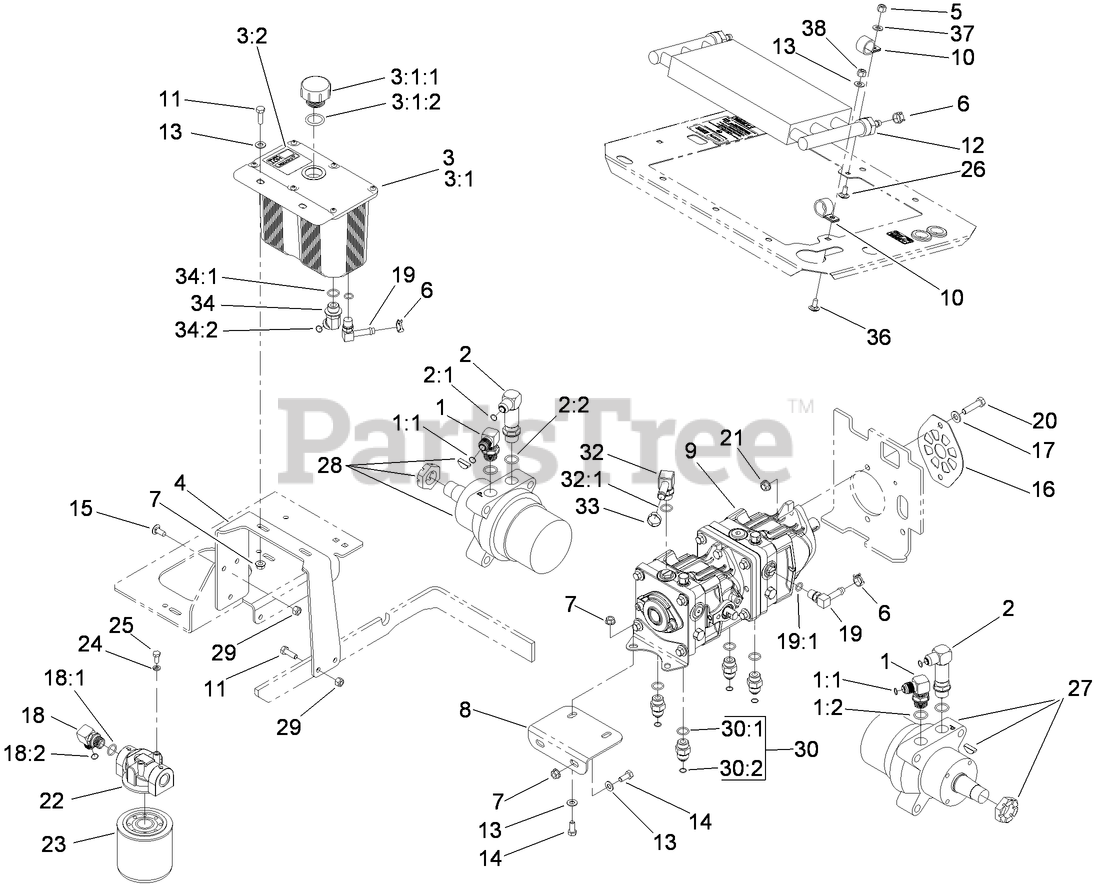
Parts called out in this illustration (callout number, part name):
1	FITTING-HYD, 90 DEG
1:1	O-Ring
1:2	O-RING
2	FITTING-ELBOW-90
2:1	O-Ring
2:2	O-RING
3	HYDRAULIC TANK ASM
3:1	TANK-HYDRAULIC
3:1:1	CAP-RESERVOIR, HYD
3:1:2	GASKET-CAP
3:2	DECAL-TANK, HYD
4	BRACKET-TANK, HYDRAULIC
5	NUT-LOCK, NI
6	CLAMP-HOSE
7	NUT-HF
8	BRACKET-PUMP, FRONT
9	TANDEM PUMP ASM
10	R-CLAMP
11	SCREW-HH
12	COOLER-OIL, HYDRO
13	WASHER-PLAIN
14	SCREW-HH
15	SCREW-CARR
16	PLATE-SHIELD, PUMP
17	WASHER-FLAT
18	FITTING-90 DEG
18:1	O-RING
18:2	O-Ring
19	FITTING-ELBOW, 90
19:1	O-RING
20	SCREW-HH
21	NUT-HHF, WHIZ
22	HEAD-FILTER
23	CARTRIDGE-FILTER, OIL
24	WASHER-LOCK
25	SCREW-HH
26	SCREW-CARR
27	HYD MOTOR ASM (CCW)
28	HYD MOTOR ASM (CW)
29	NUT-LOCK, NI
30	FITTING-STRAIGHT
30:1	O-RING
30:2	O-Ring
32	FITTING-ELBOW, 90 DEG
32:1	O-RING
33	CLAMP-HOSE
34	FITTING-HYD, 45 DEG
34:1	O-RING
34:2	O-Ring
36	SCREW-CARR
37	WASHER-FLAT
38	NUT-LOCK, NI
